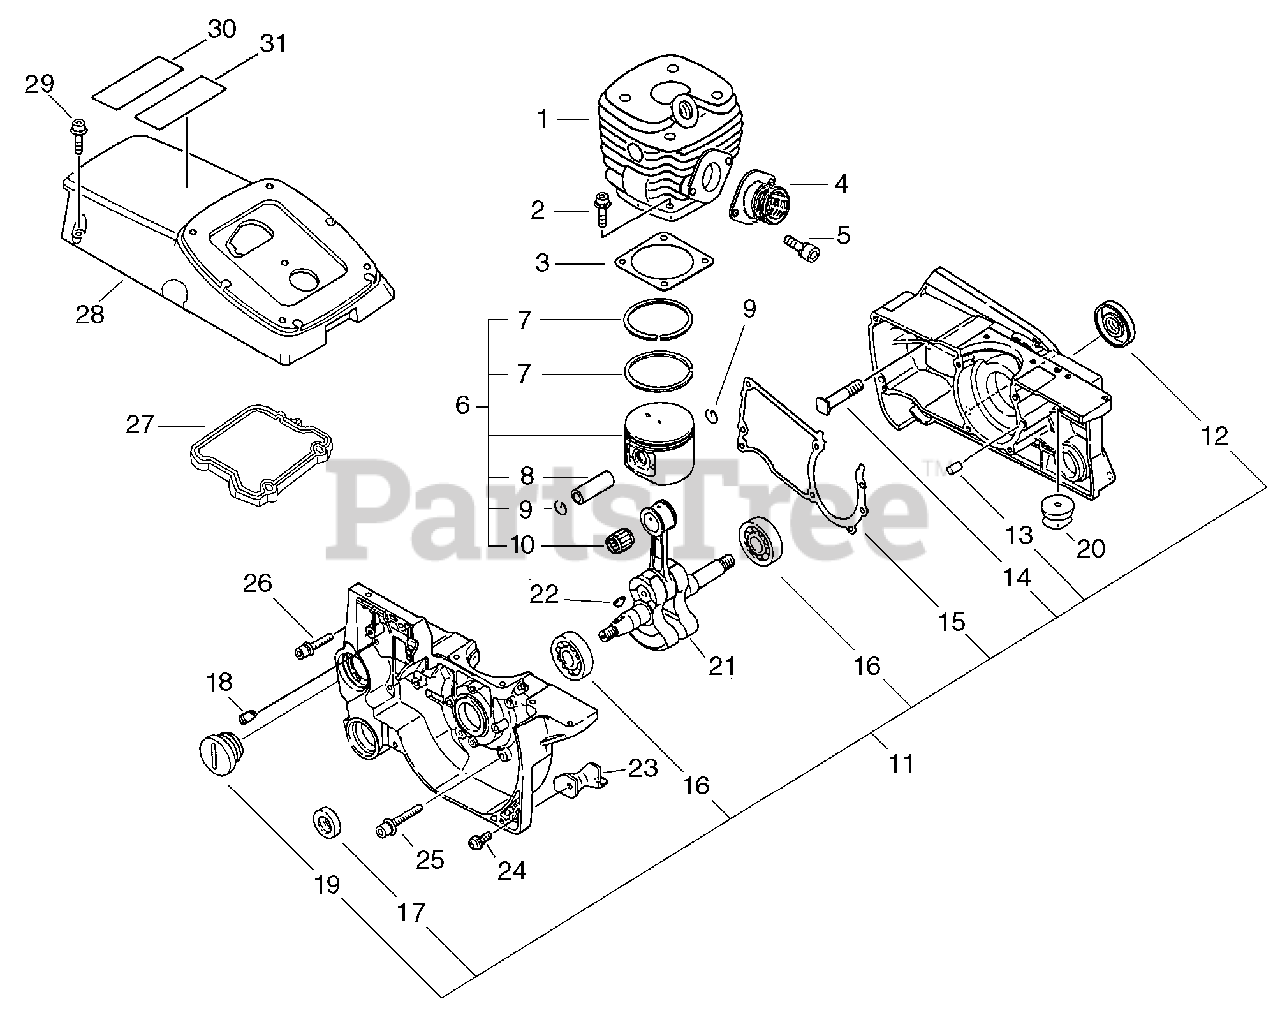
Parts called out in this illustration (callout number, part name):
1	CYLINDER
2	BOLT 5×25
3	GASKET, CYLINDER
4	BELLOWS, INTAKE
5	BOLT 4×14
6	PISTON KIT
7	RING, PISTON
8	PIN, PISTON 12
9	RING, SNAP
10	BEARING, NEEDLE
11	CRANKCASE KIT
12	SEAL, OIL
13	PIN, LOCATING 5×10
14	STUD, GUIDE BAR
15	GASKET, CRANKCASE
16	BEARING, BALL 6202
17	SEAL, OIL
18	VENT ASSY
19	CAP, OIL TANK
21	CRANKSHAFT ASSY
22	KEY, WOODRUFF
24	SCREW 5×14
25	BOLT M5×35
26	BOLT 5×20
27	CUSHION
28	COVER, ENGINE
29	BOLT 5×20
30	LABEL, CAUTION
31	LABEL, CAUTION
